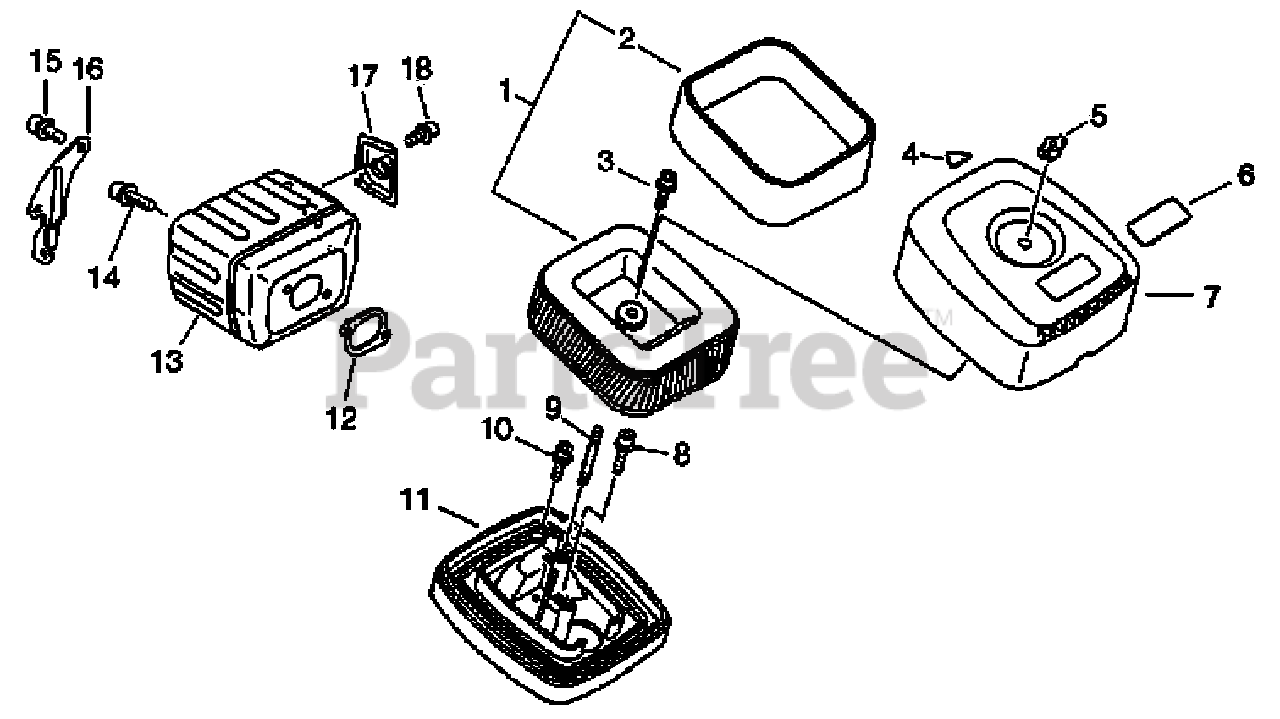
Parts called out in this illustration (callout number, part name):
1	FILTER, AIR
2	FILTER, AIR
3	BOLT - 5×16
6	LABEL - MODEL CSG-680
7	COVER, AIR FILTER
8	SCREW 5×25
10	SCREW 5×16
11	CASE, AIR FILTER
12	GASKET, EXHAUST
13	MUFFLER
14	BOLT 5×20
15	BOLT 5×10
16	BRACKET, MUFFLER
17	GUIDE, EXHAUST
18	BOLT 4×10
